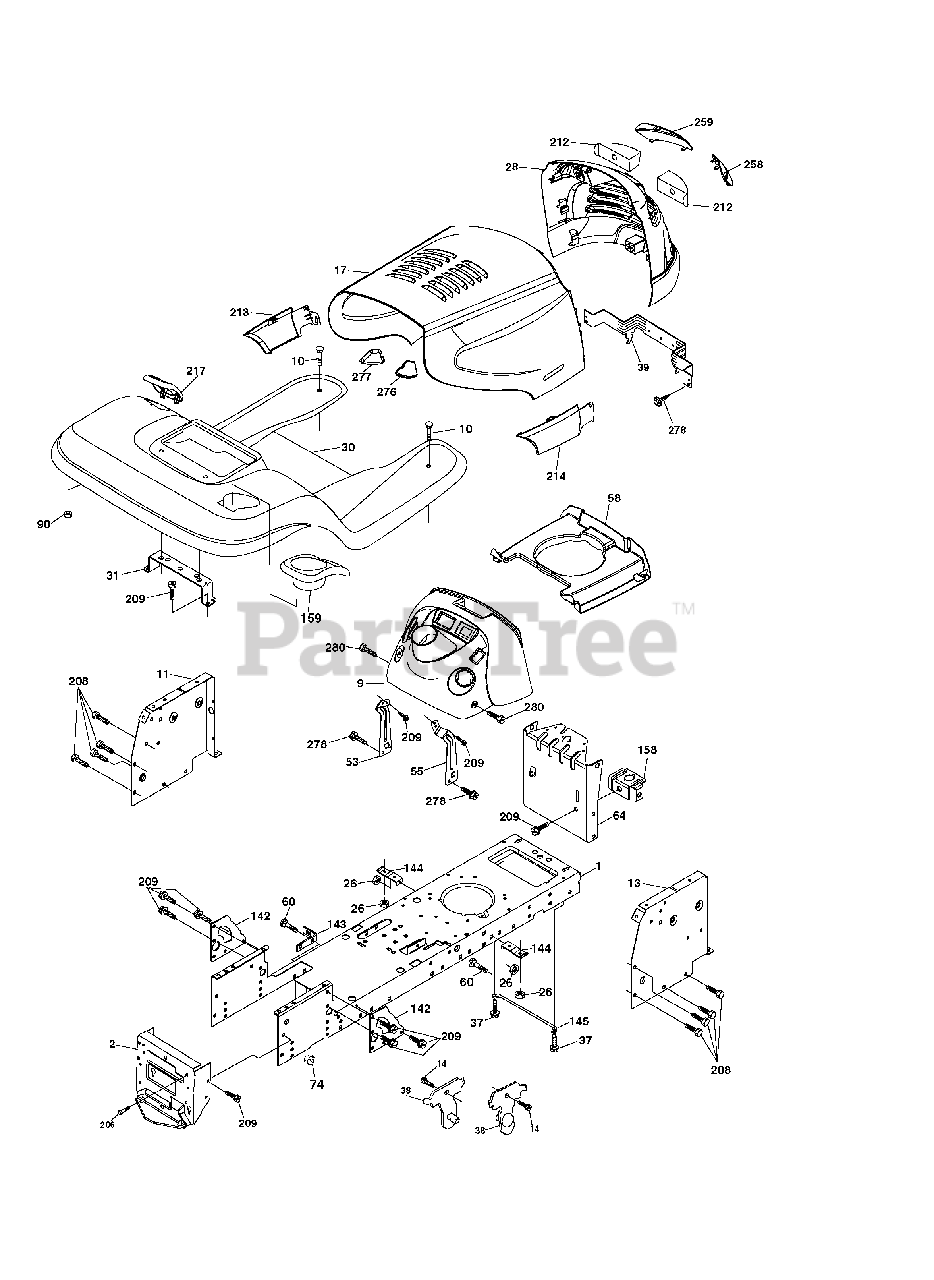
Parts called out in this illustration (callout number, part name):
1	Chassis
10	Bolt Carriage 3/8-16 x 1
11	Panel Dash Lh
13	Panel Dash Rh
14	Screw Thdrol 3/8-16 x 1/2
17	Hood
26	Nut Lock Hex W/Ins 3/8-16 unc
28	Grille/Lens Asm.
30	Fender Footrest
31	Bracket Fender
37	Screw Thdrol 6/16-18 x 1/2 TYT
38	Bracket Asm Pivot Mower Rear
39	Bracket Pivot Hood
53	Bracet Dash LH
55	Bracket Dash RH
60	Bolt RDHD Sqnk 3/8-16 unc x 3/4
64	Dash Lower STLT
74	Nut Crownlock 3/8-16 unc
90	Nut Self Thd Wsh - HD 1/4 Zinc
142	Plate Reinforcement STLT
143	Bracket Swaybar Chassis
144	Bracket Footrest Step-thru
145	Rod Pivot Chassis/Hood
158	Bracket Parking Brake
159	Cupholder
206	Bolt Shoulder 5/16-18
208	Screw Thdrl 3/8-16 x 1/2
209	Screw Hexwsh Thdr 3/8-16 x 3/4
212	Insert Lens
213	Skirt Grille LH
214	Skirt Grille RH
217	Console Fuel Window
258	Lens RH
259	Lens LH
276	Bumper Hood RH
277	Bumper Hood LH
278	Screw 10 x 3/4 Single Lead-Hex
280	Screw 3/8-16 x 1
